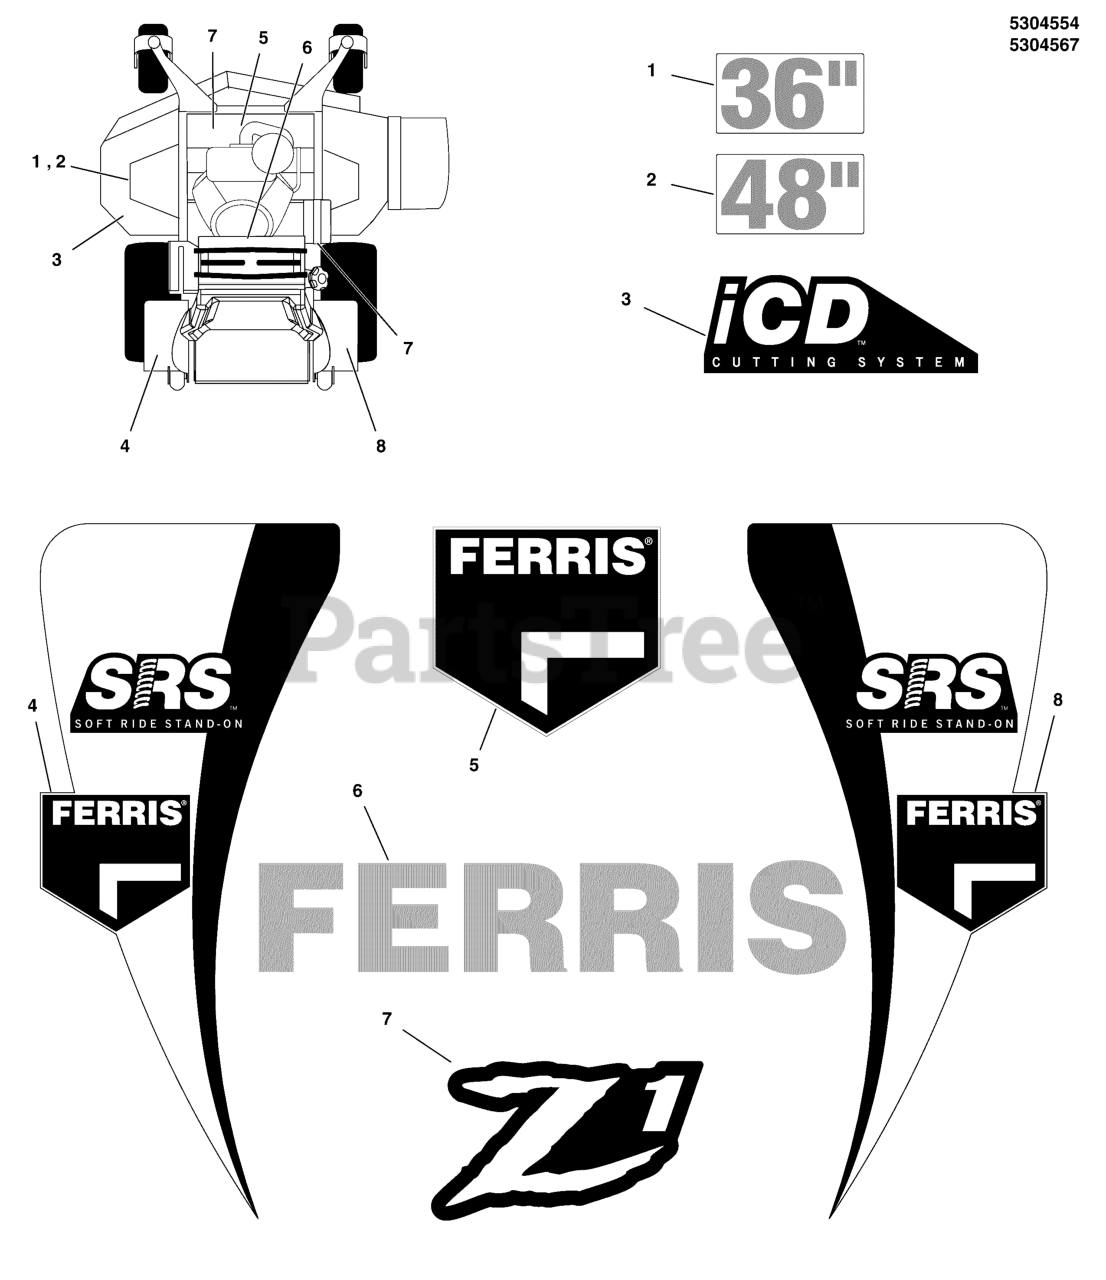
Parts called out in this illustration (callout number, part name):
1	DECAL, 36
2	DECAL, 48
3	DECAL, ICD CUTTING SYSTEM
4	DECAL, FENDER, SRSZ1 / Z2, LH
5	DECAL, BRAND
6	DECAL, FERRIS, 1.796 X 9.00
7	DECAL, MODEL, Z1
8	DECAL, FENDER, SRSZ1 / Z2, RH
